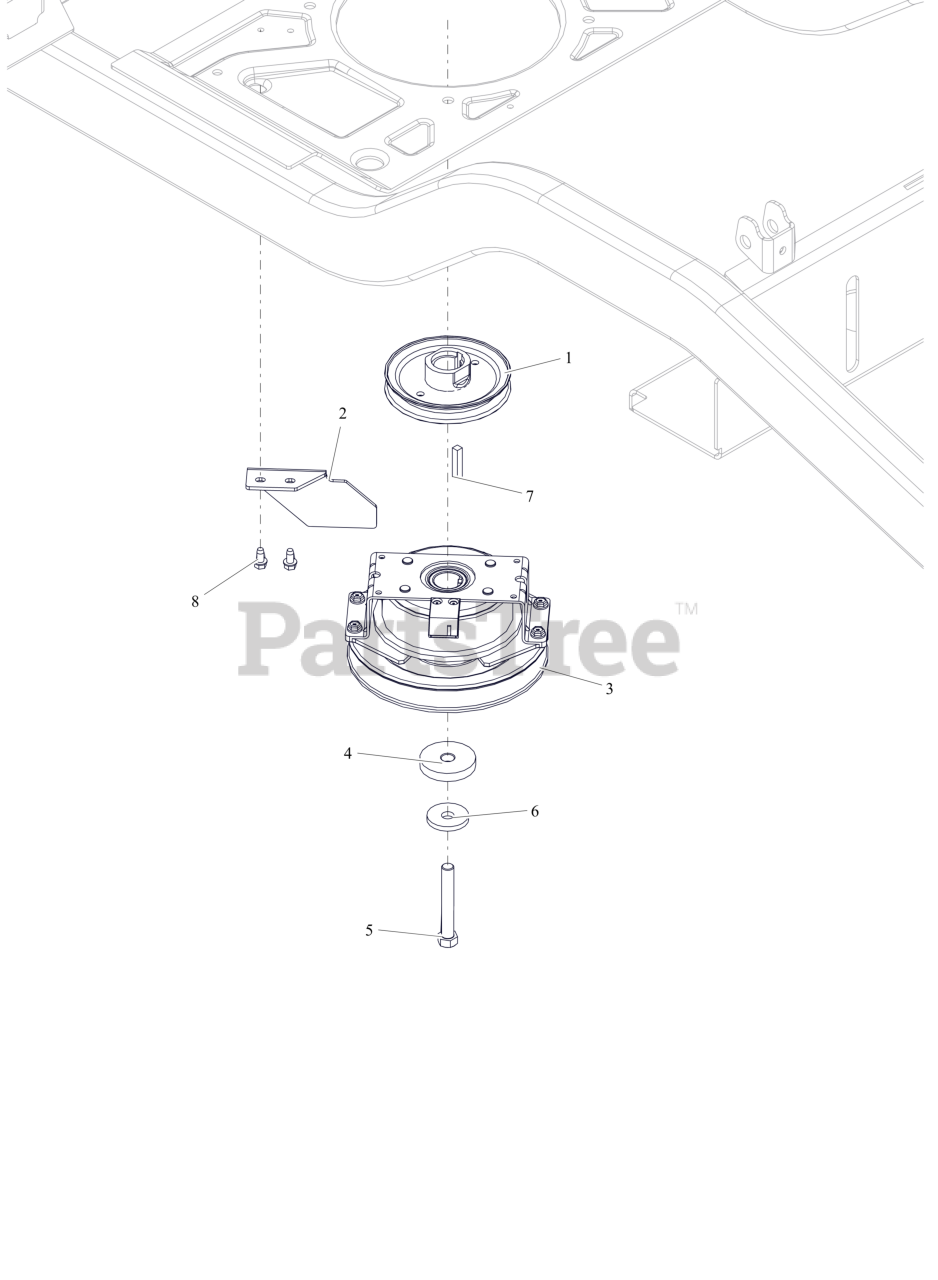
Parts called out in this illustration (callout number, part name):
1	WLDMT,PULLEY-4.50ODX1.003
2	BRKT, CLUTCH STOP HD
3	CLUTCH, OGURA DBL SPRG
4	SPACER, .474/.459X2.00X.350
5	BLT, HEX .44-20X3.00 G8 ZCC NT
6	WASHER, 7/16" SPRING DISK
7	KEY-SQ .25 X 1.25 X .25 SAE
8	SCR-TAP .25-20X.50 HWH ZCC
